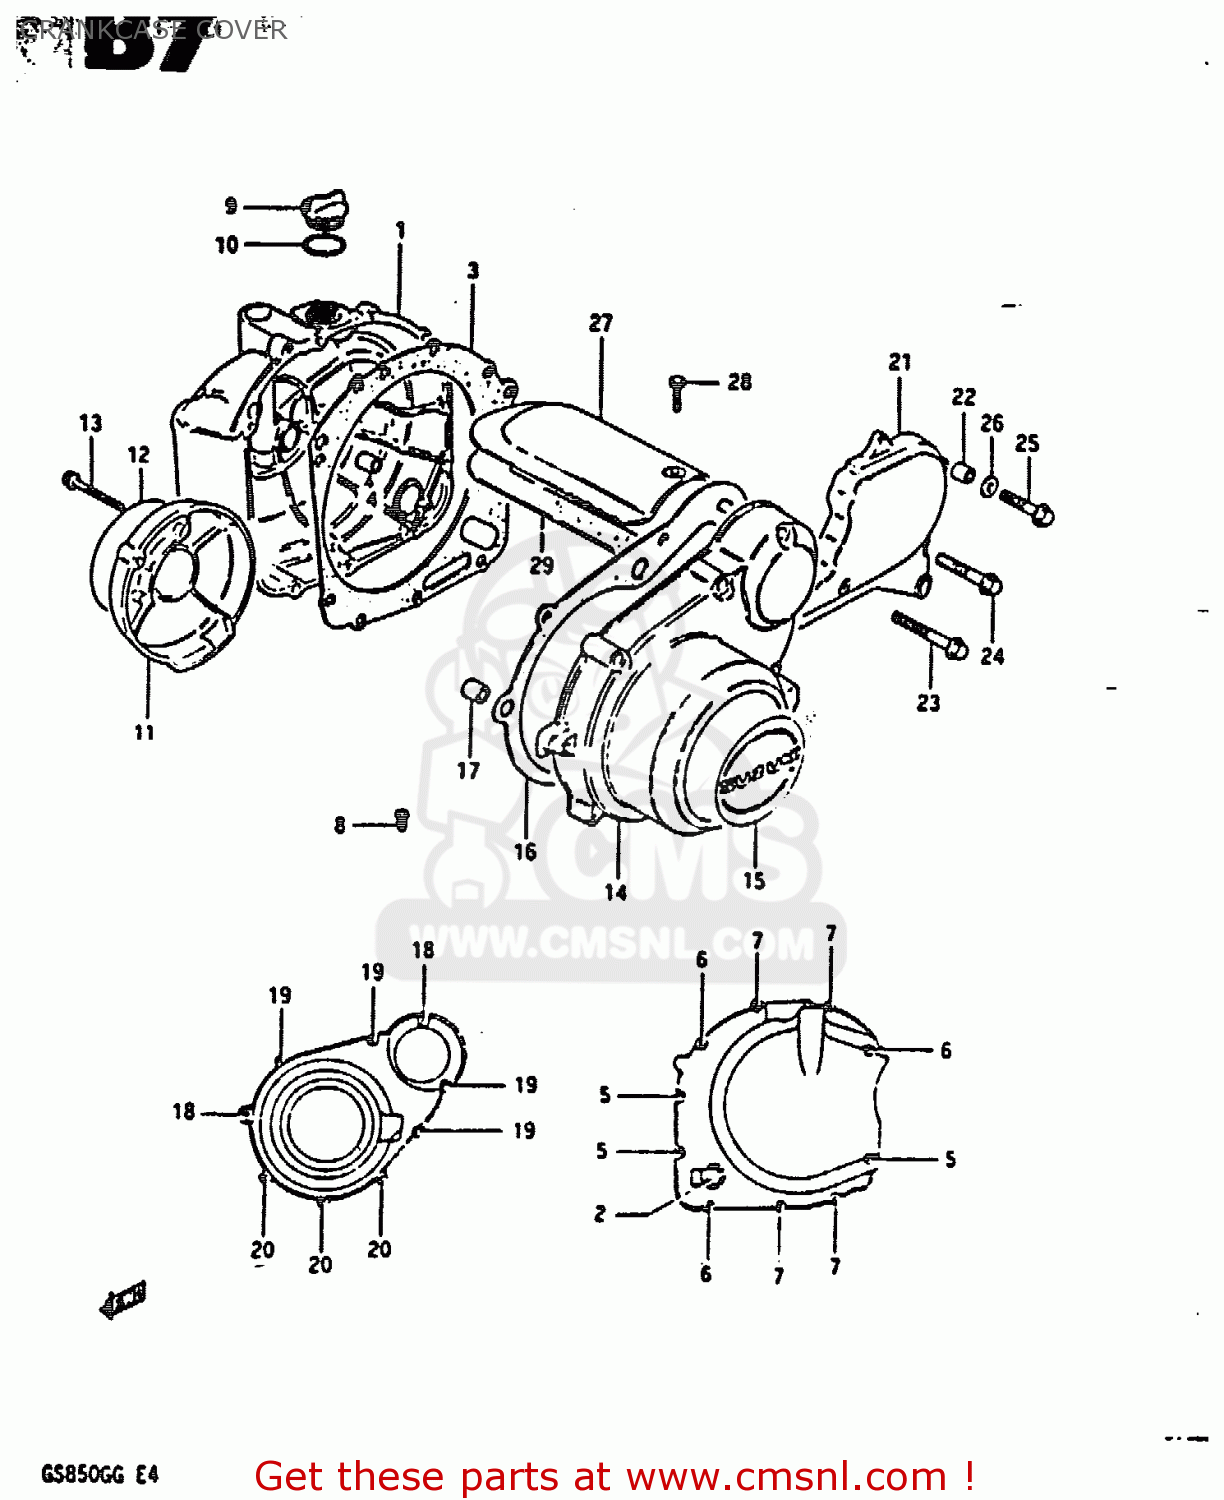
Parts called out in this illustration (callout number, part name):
1	COVER,CLUTCH
2	LENS,OIL LEVEL CHECK
3	GASKET,MAGNETO COVER (N (MCA)
4	PIN
5	BOLT
6	BOLT
7	BOLT
8	JET
9	PLUG SET
10	O RING(D:2.2,ID:32)
11	COVER,CONTACT BREAKER
12	EMBLEM,CONTACT BREAKER COVER
13	BOLT
14	COVER,MAGNETO
15	EMBLEM,MAGNETO COVER
16	GASKET,MAGNETO COVER (MCA)
17	PIN
18	BOLT
19	BOLT
20	BOLT
21	COVER,SPROCKET
22	PIN
23	BOLT
24	BOLT (6X20)
25	BOLT
26	WASHER
27	COVER,STARTER MOTOR
28	BOLT
29	GASKET,STARTING MOTOR COVER (NAS)
